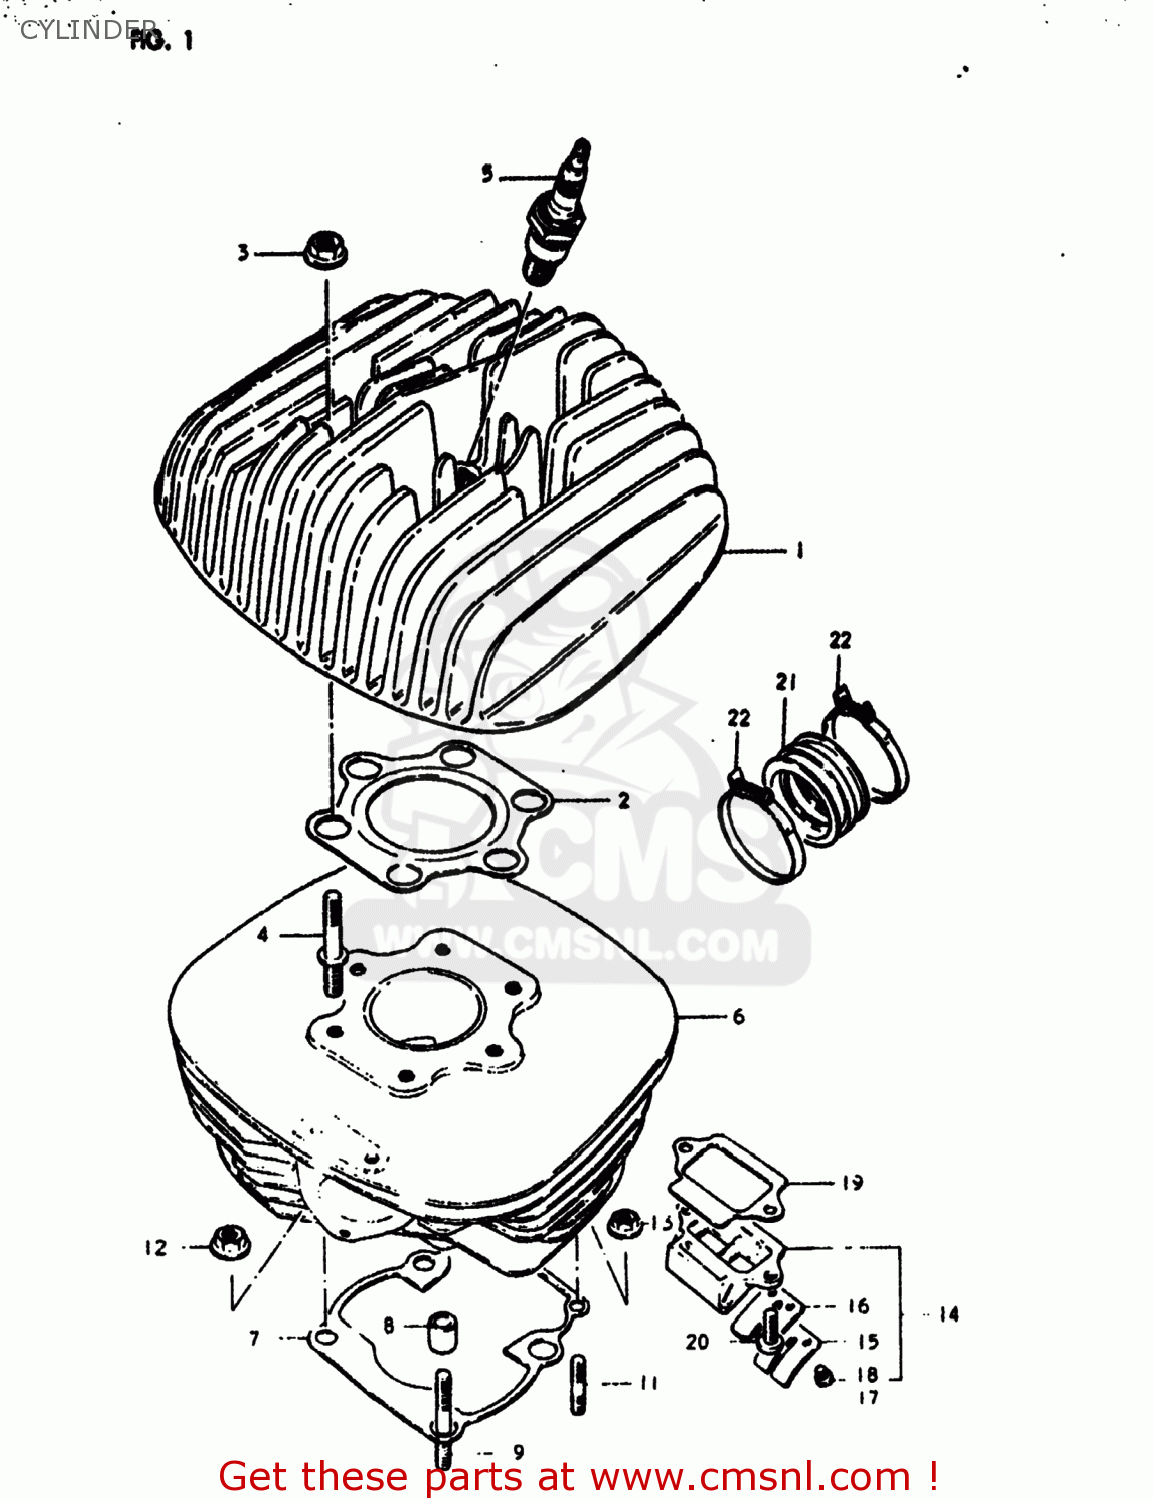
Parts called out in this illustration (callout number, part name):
1	HEAD,CYLINDER
2	GASKET,CYLINDER HEAD (NAS)
3	NUT
4	BOLT,STUD
5	SPARK PLUG
6	CYLINDER
7	GASKET,CYLINDER (MCA)
8	PIN
9	STUD 8X40
11	STUD 6X20
12	NUT
13	NUT
14	VALVE ASSY,REED
15	STOPPER,REED VALVE
16	VALVE,REED
17	SCREW
18	LOCK WASHER
19	GASKET,REED VALVE (MCA)
20	SCREW
21	PIPE,INTAKE
22	CLAMP
